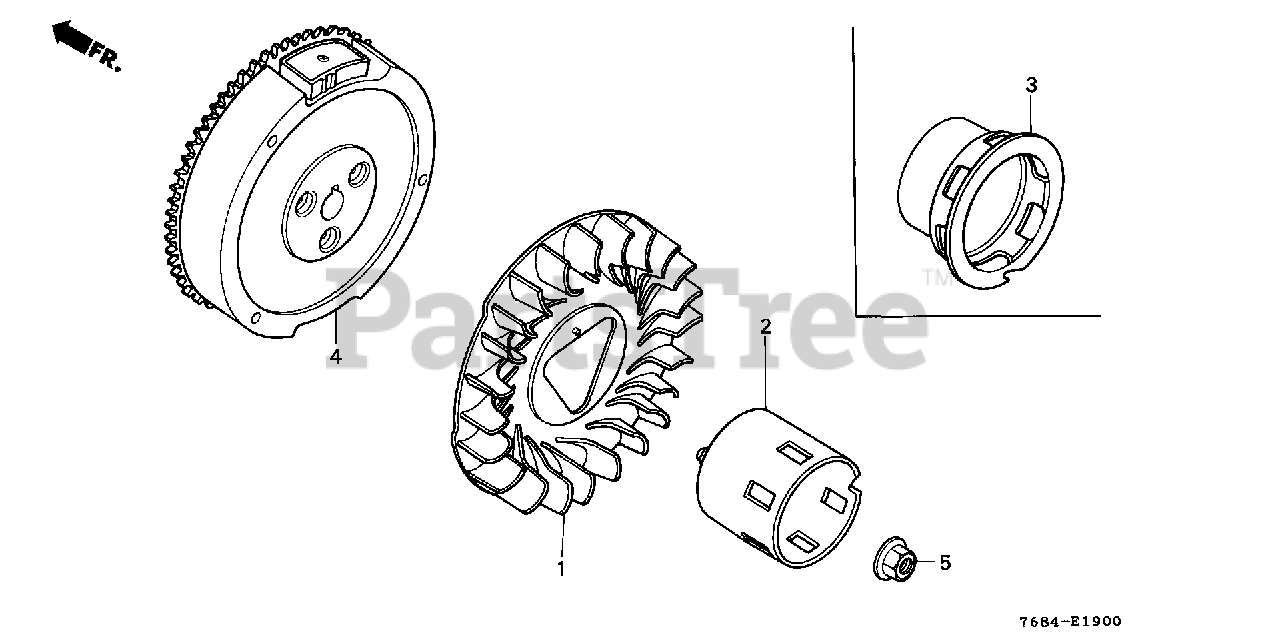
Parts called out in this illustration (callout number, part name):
1	FAN, COOLING
3	PULLEY, STARTER
4	FLYWHEEL (4POLE)
5	NUT, SPECIAL (16MM)
